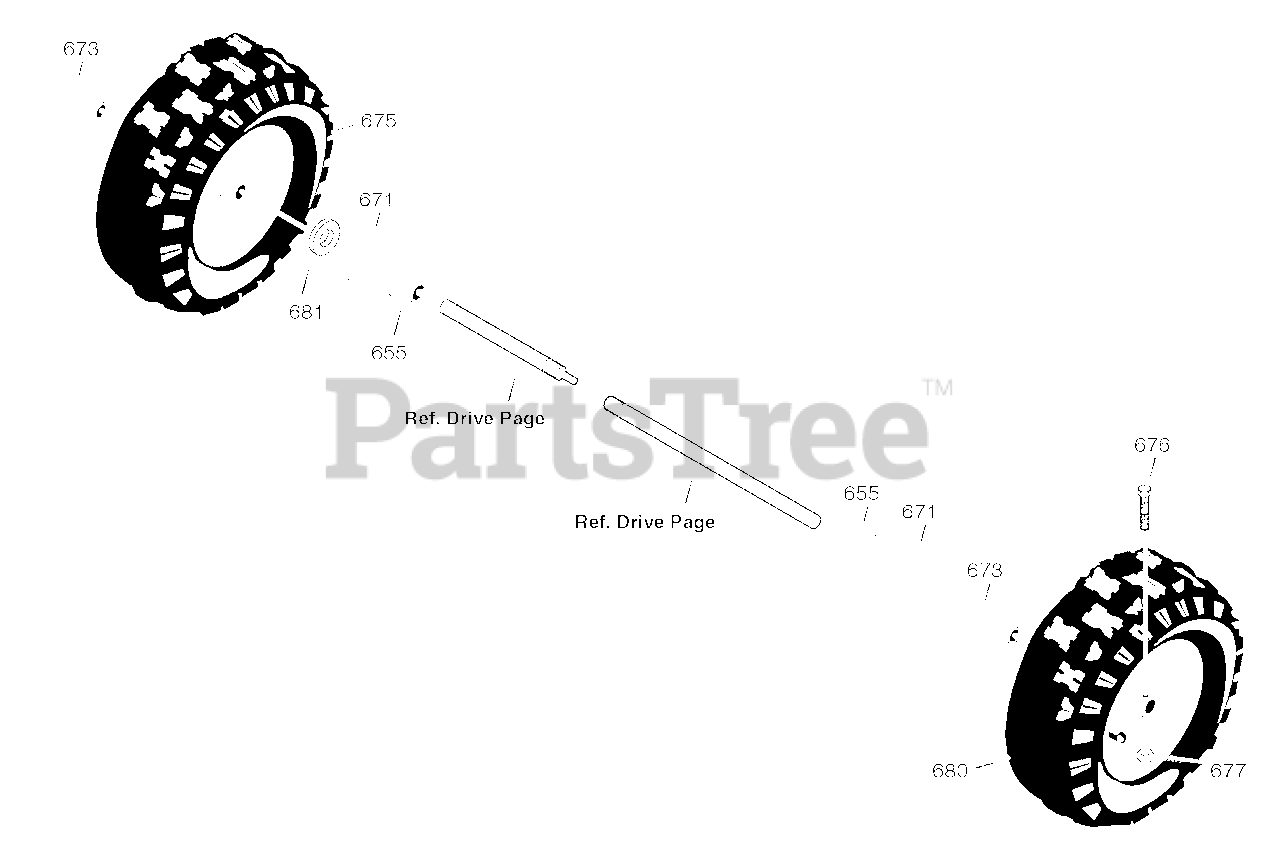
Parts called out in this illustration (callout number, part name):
655	BEARING, AXLE
671	FLATWASHER
673	BUSHING, WHEEL
675	TIRE & RIM, RIGHT
676	SCREW, 1/4-20X1.75 HH
677	NUT, 1/4-20 HEX NYLOCK
680	TIRE & RIM, LEFT
681	RETAINER
